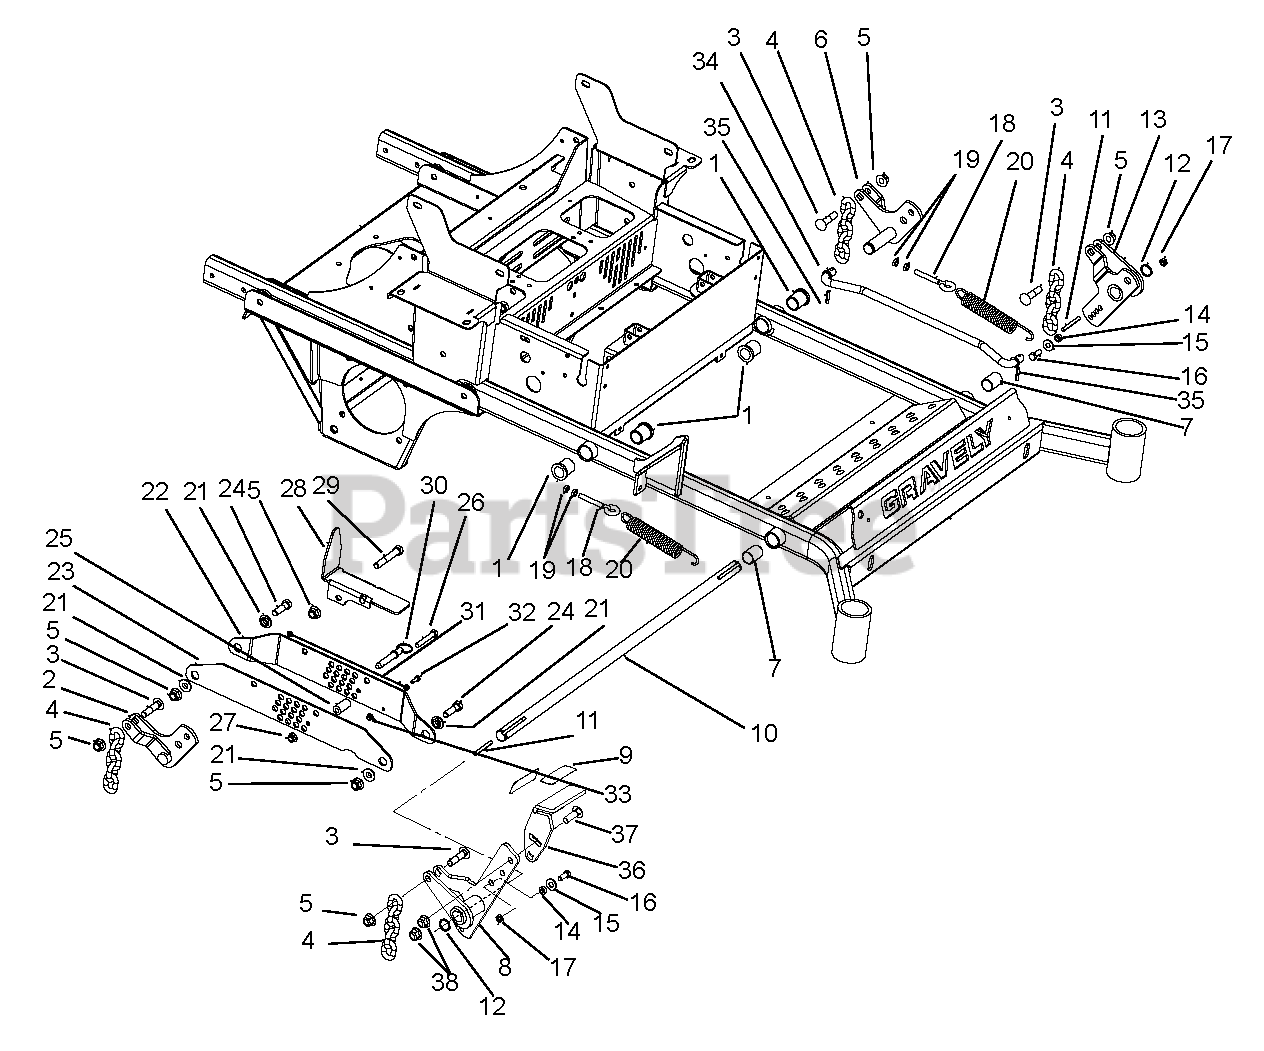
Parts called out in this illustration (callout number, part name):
1	Bushing, Flange 1.00 x 1.25 x 1.50 x 1.50
2	Weldment, Right Hand Rear Deck Lift
3	Bolt, Round Head Square Neck .50-13 x 2.25 G5YZ
4	Chain, 5 Link 3/8 Mower Lift
5	Nut, Locking Nylon Flange .50-13
6	Weldment, Left Hand Rear Deck Lift
7	Bushing,1.00ID x 1.125OD x 1.50LG
8	Weldment, Adjustable Deck Foot Lift
9	Grip Pedal 1.50 x 3.00
10	Shaft, Front Mower Lift
11	Key, Square .25 x 2.50 x .25 SAE
12	Ring, Retaining External 1.00 x .078
13	Weldment, Front Left Hand Deck Lift
14	Bushing, Sleave .377 x .624 x .235
15	Washer, Flat Steel .438 x 1.00 x .083
16	Bolt, Hex .38-16 x 1.00 GR5
17	Nut, Locking Center Jam .375-16
18	Bolt, Eye .375-16 x 2.50
19	Nut, Hex Jam .375-16
20	Spring, Tension .162 x 1.25 x 8.25 WLD 25
21	Bushing, Flange .515 x .750 x .395 x 1.120
22	Bracket, Right Hand Lift/Cut Height Inboard
23	Bracket, Right Hand Lift/Cut Height Outboard
24	Bolt, Hex .50-13 x 1.75 GR5
25	Spacer, .375 x .750 x 1.54
26	Bolt, Hex .38-16 x 2.50 GR5
27	Nut, Locking Nylon Flange .38-16
28	Weldment, Mechnical Lock-Up
29	Bolt, Hex .50-13 x 3.25 GR5
30	Pin, .50 x 2.00
31	Cable, 12.0 Lanyard, Nylon
32	Bolt, Hex .25-20 x .75 GR5
33	Nut, Locking Nylon Flange .25-20
34	Rod, Lift Assist 19.35"
35	Pin, Roll .250 x 1.25 Stainless Steel
36	Adjustable Foot Lift Pedal, Black
37	Bolt, Round Head Square Neck .50 x 13 x 1.50 Grade 5 YZ
38	Nut, Locking Nylon Flange .50-13
